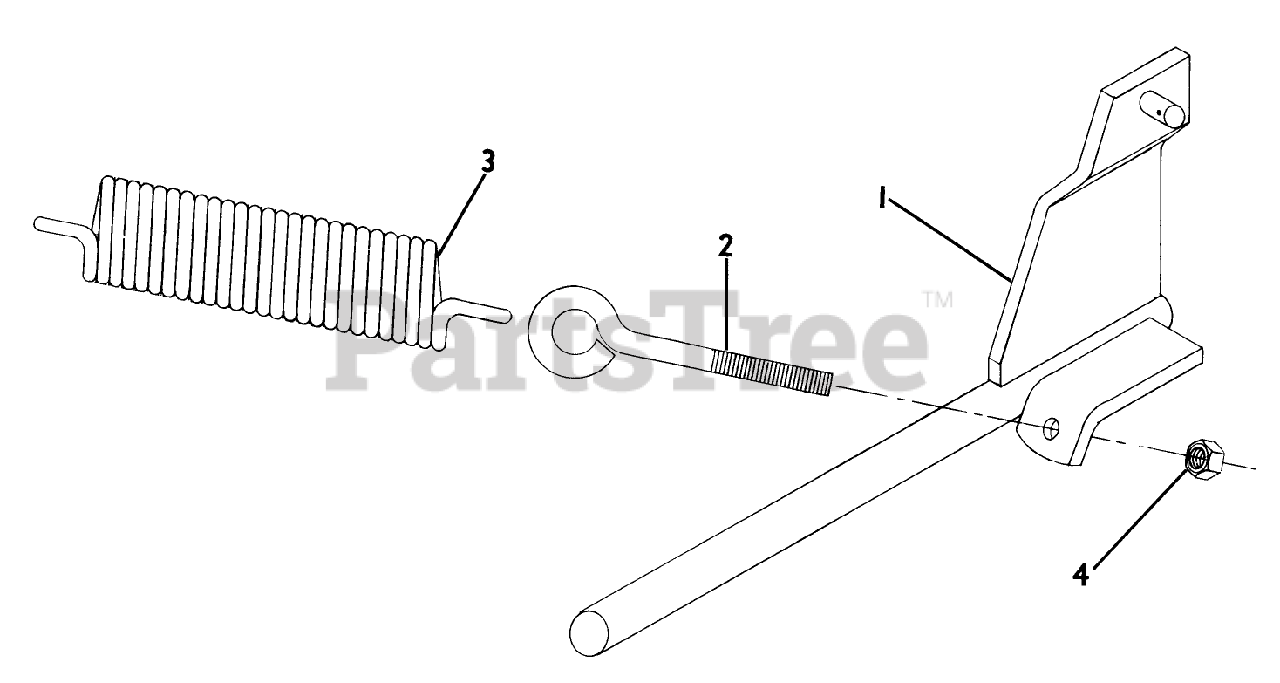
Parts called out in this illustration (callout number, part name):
1	LIFT ROD ASM
2	EYEBOLT
3	SPRING
4	3/8-16 E.S.
